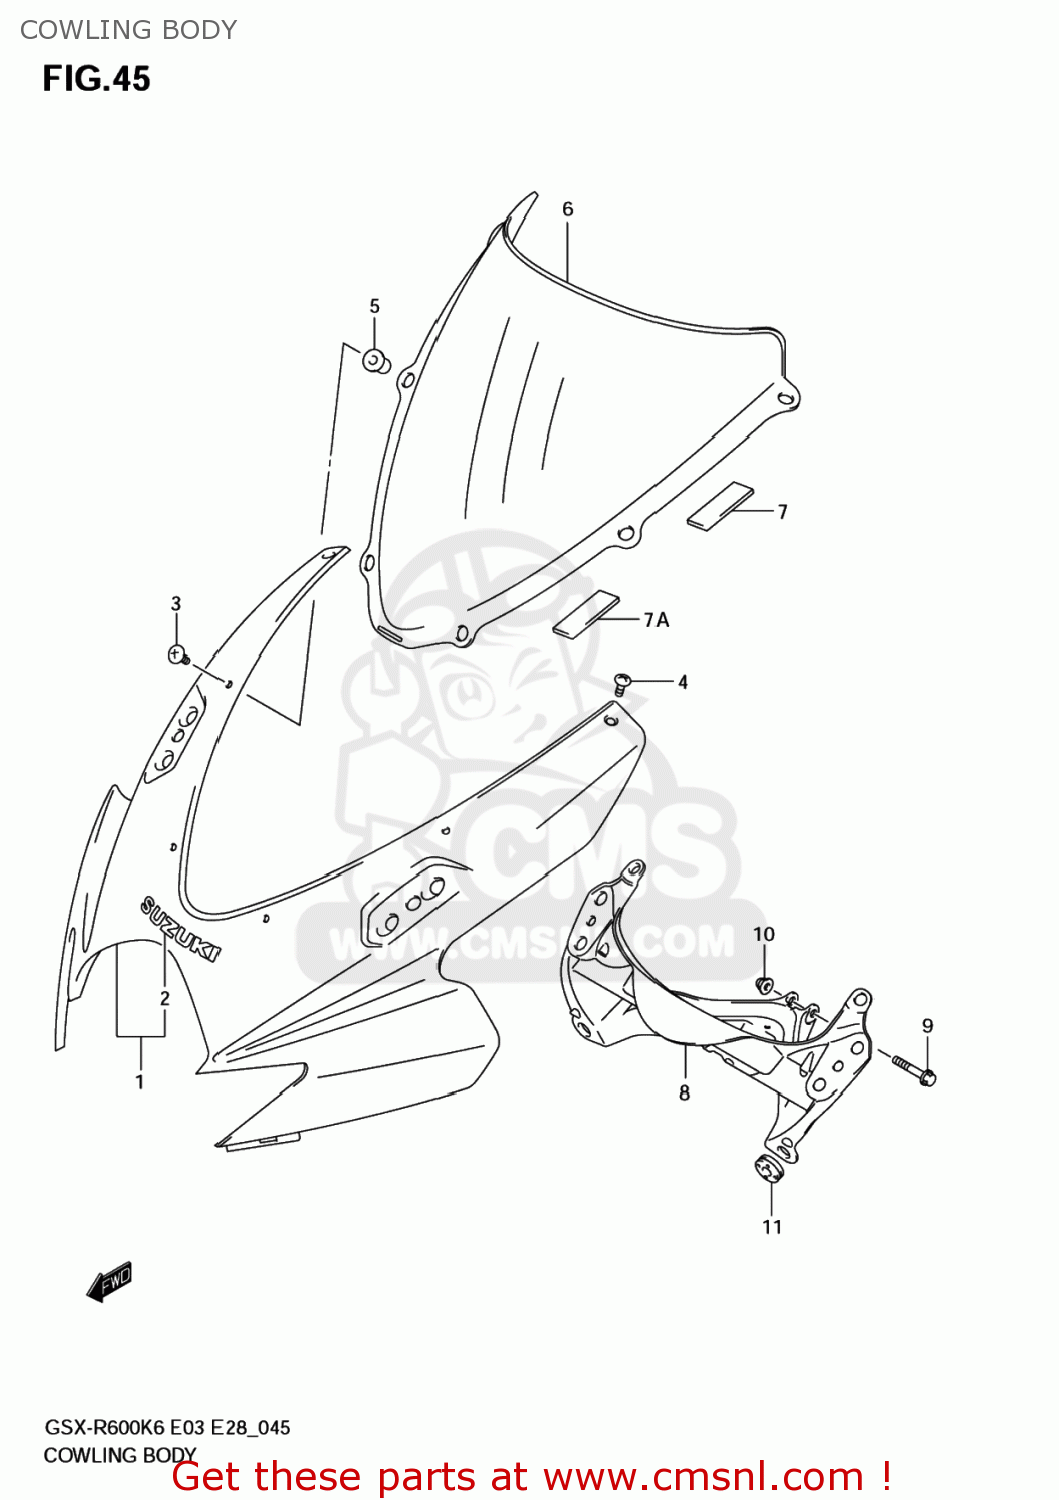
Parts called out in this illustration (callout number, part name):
1	BODY ASSY,COWLING
2	EMBLEM,SUZUKI
3	SCREW(5X18)
4	SCREW(5X15)
5	NUT
6	WINDSCREEN
7	TAPE(6X25X0.13)
7A	CUSHION,WINDSCREEN
8	BRACE,COWLING
9	BOLT
10	NUT
11	CUSHION
